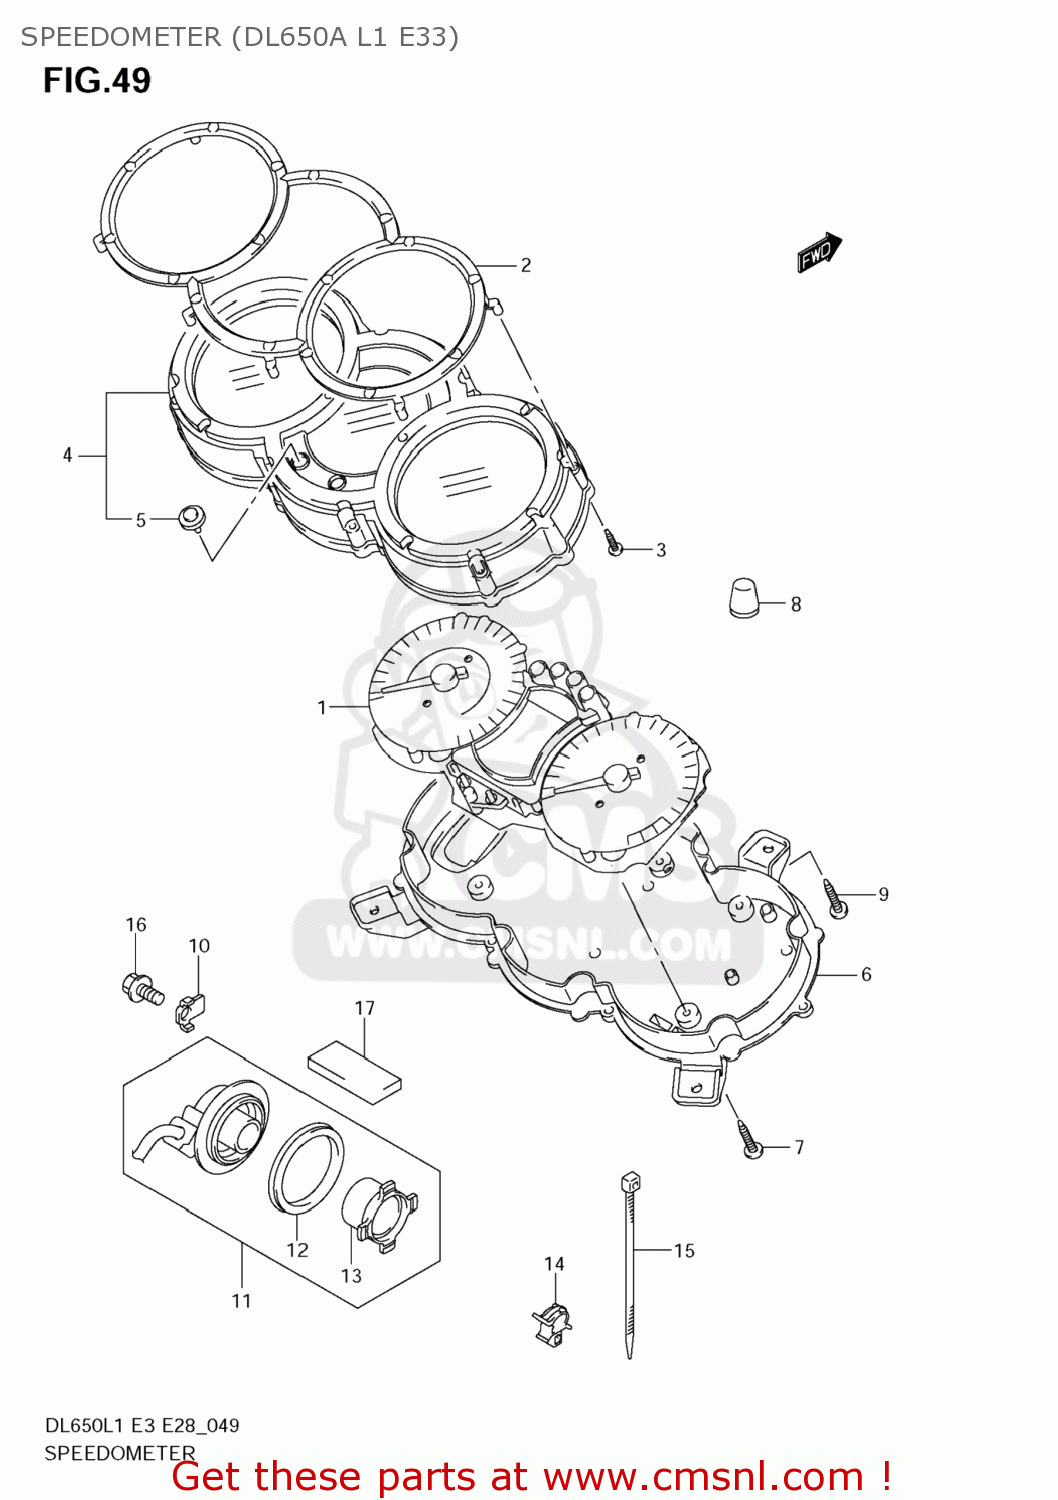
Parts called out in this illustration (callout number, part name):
1	SPEEDOMETER
2	COVER
3	SCREW(2.3X8)
4	CASE,UPR
5	SWITCH,LEVER
6	CASE,LWR
7	SCREW(3X16)
8	CUSHION,SPEEDOMETER
9	SCREW
10	GUIDE,SENSOR LEAD
11	SENSOR,SPEED
12	SEAL,OIL(44X55X6)
13	MAGNETO
14	CLAMP
15	CLAMP(L:145)
16	BOLT
17	PROTECTOR(18X45X5)
